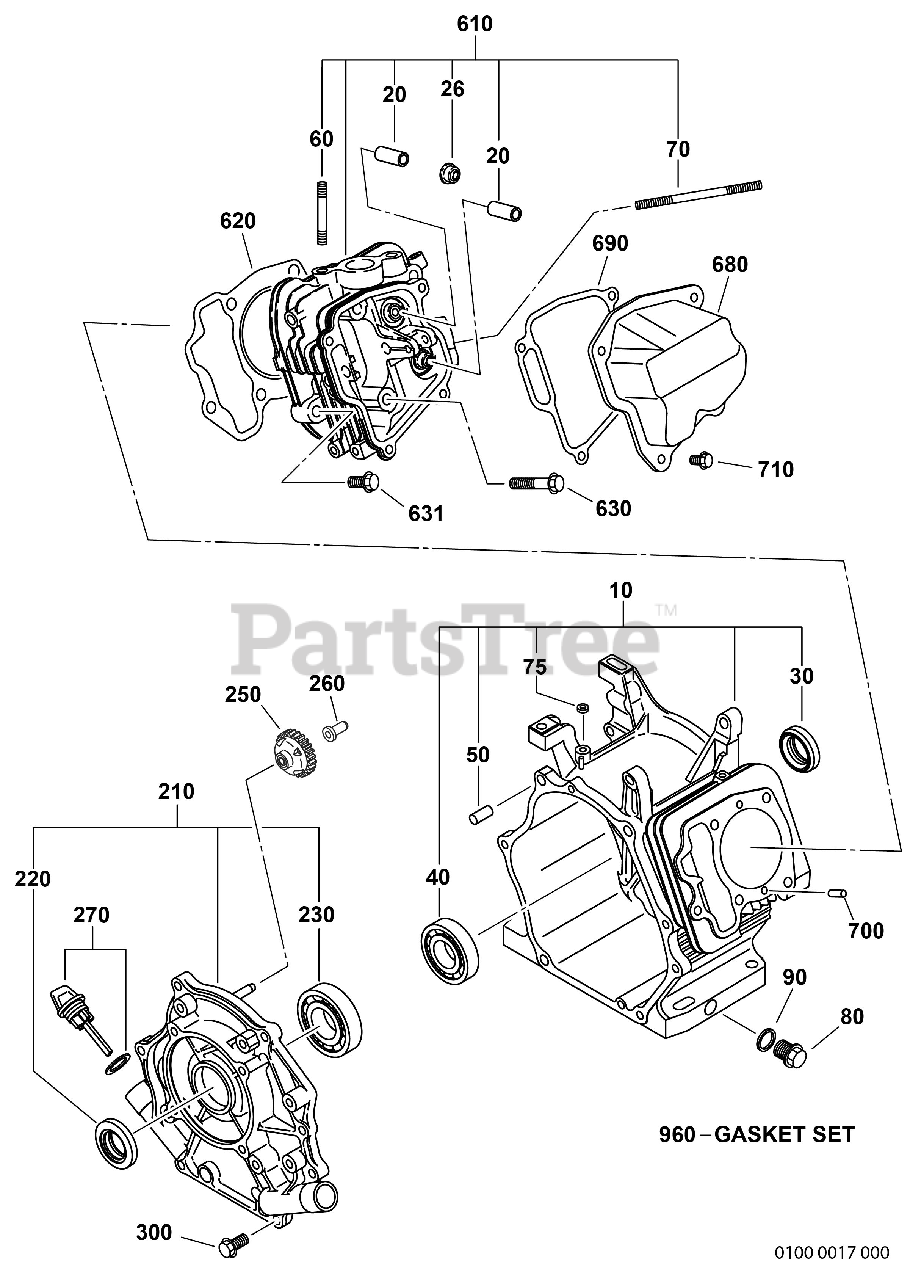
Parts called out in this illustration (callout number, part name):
10	CRANKCASE CP
20	VALVE GUIDE
26	STEM SEAL
30	OIL SEAL
40	BALL BEARING
60	STUD
70	STUD
80	OIL DRAIN PLUG
210	MAIN BEARING COVER CP
250	GOVERNOR GEAR CP
260	GOVERNOR SLEEVE
300	FLANGE BOLT
610	CYLINDER HEAD CP
630	FLANGE BOLT
631	FLANGE BOLT
680	ROCKER COVER CP
690	GASKET(ROCKER COVER)
710	FLANGE BOLT
